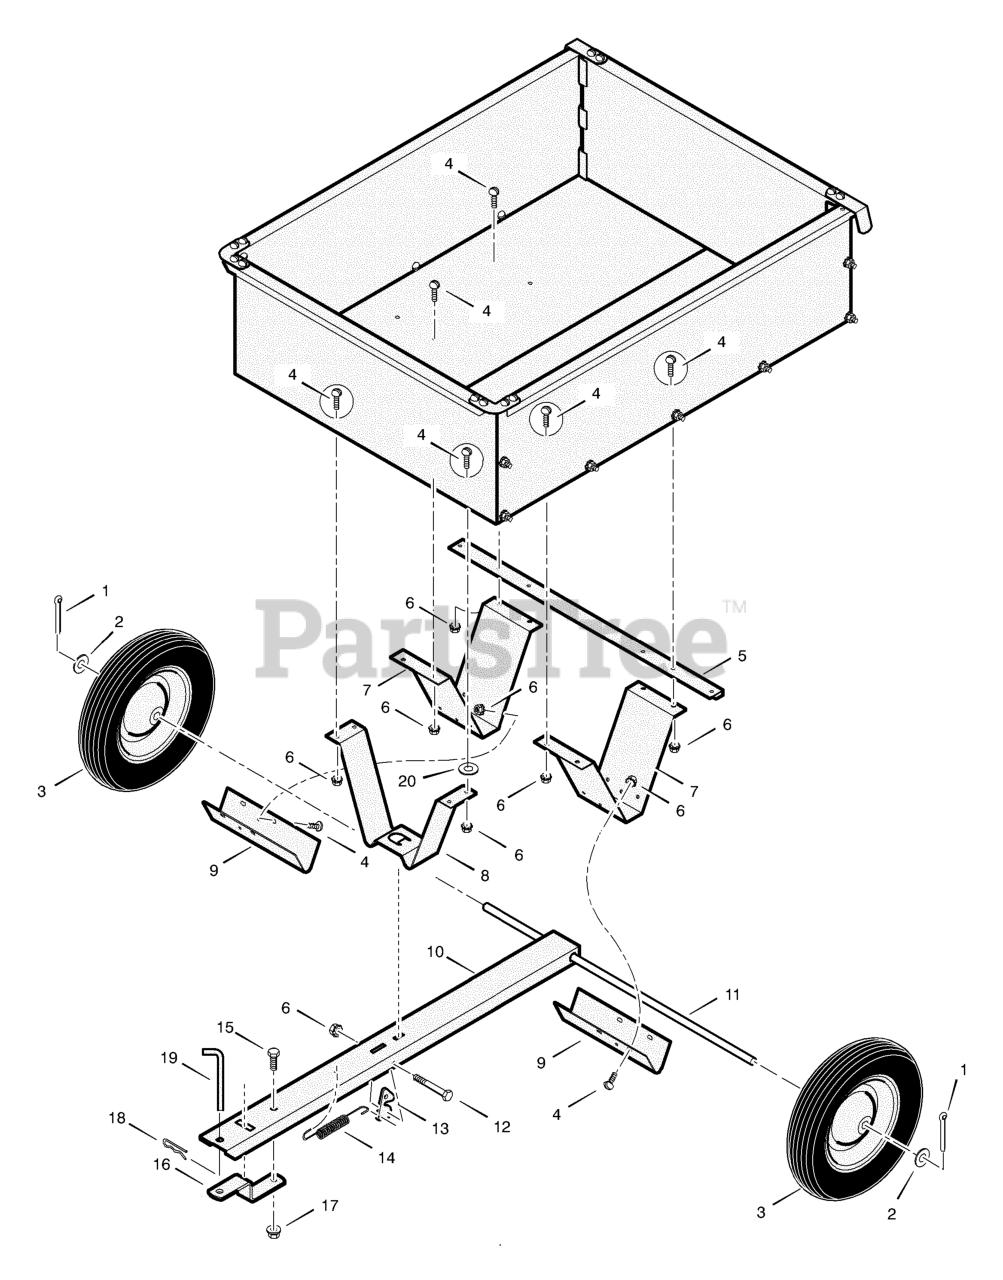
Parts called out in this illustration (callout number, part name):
1	Pin, Cotter
4	Screw 14-20x0.50
5	Support, Bottom
6	Nut, Keps 1/4-20
7	Support, Axle
8	Support, Tongue
9	Retainer, Axle
12	Bolt, Hex 1/4-20x3.25
15	Bolt, Hex 3/8-16x0.75
17	Nut, Lock 3/8-16
18	Pin, Hair
19	Pin, Drawbar
